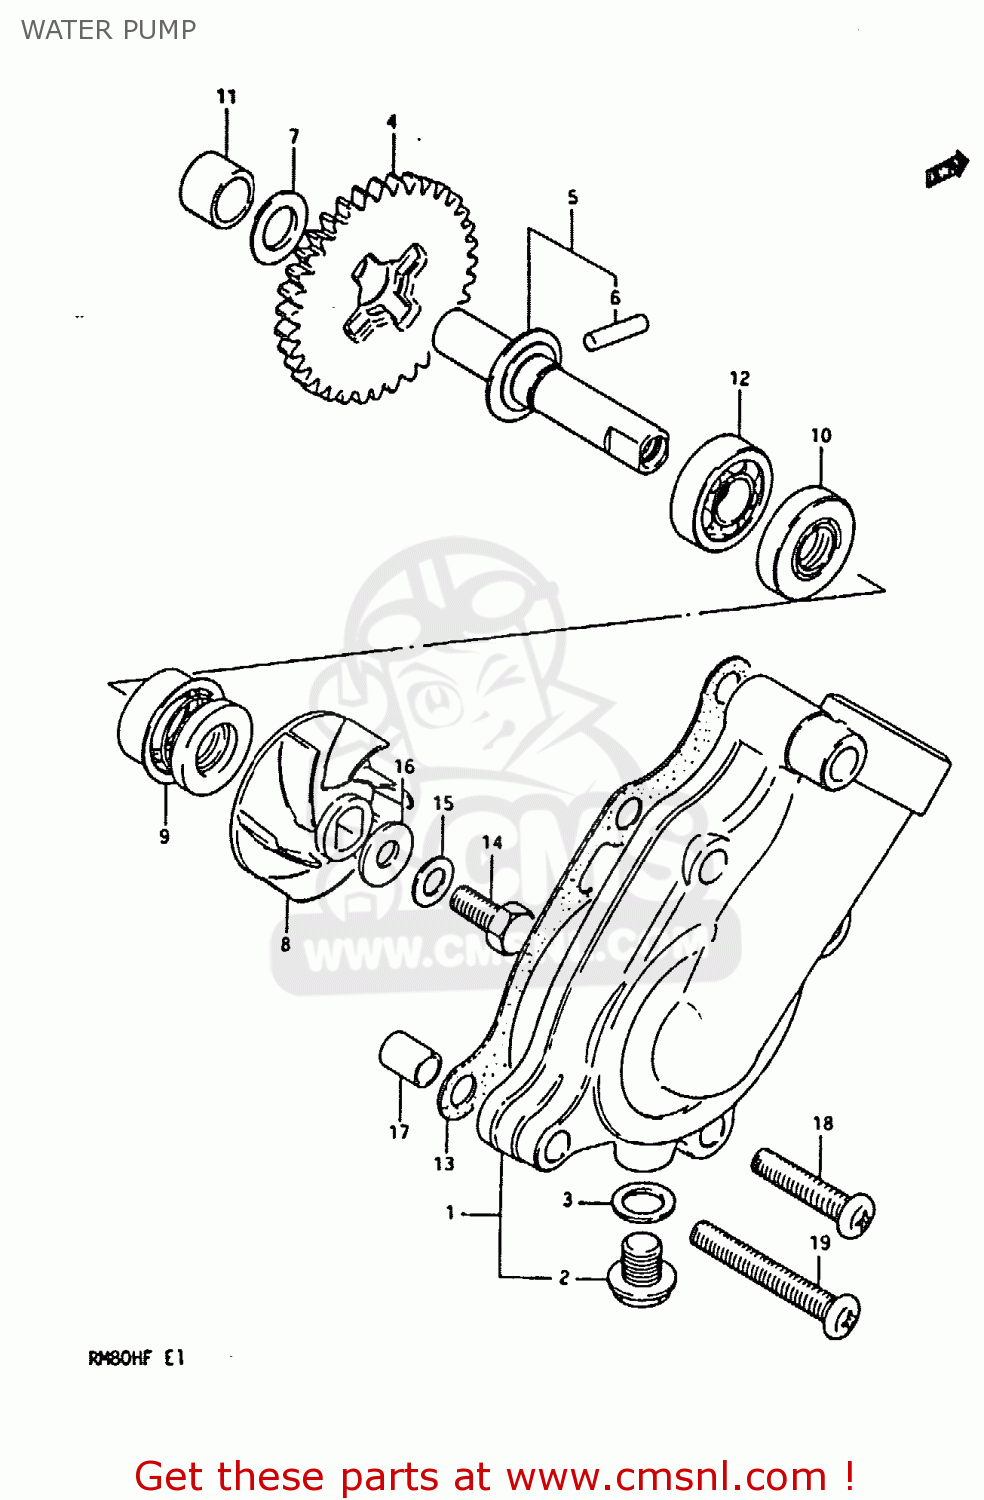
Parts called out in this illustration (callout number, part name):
1	CASE,WATER PUMP
2	BOLT,DRAIN
3	GASKET,DRAIN (NAS)
4	GEAR, DRIVEN (NT:35)
5	SHAFT,WATER PUMP
6	PIN (4X20.8)
7	WASHER,THRUST
8	IMPELLER,WATER PUMP
9	SEAL,WATER PUMP SHAFT
10	SEAL,OIL(10X21X5)
11	BUSH
12	BEARING
13	GASKET,WATER PUMP CASE (MCA)
14	BOLT(6X13)
15	WASHER
16	GASKET (NAS)
17	PIN
18	SCREW
19	SCREW
